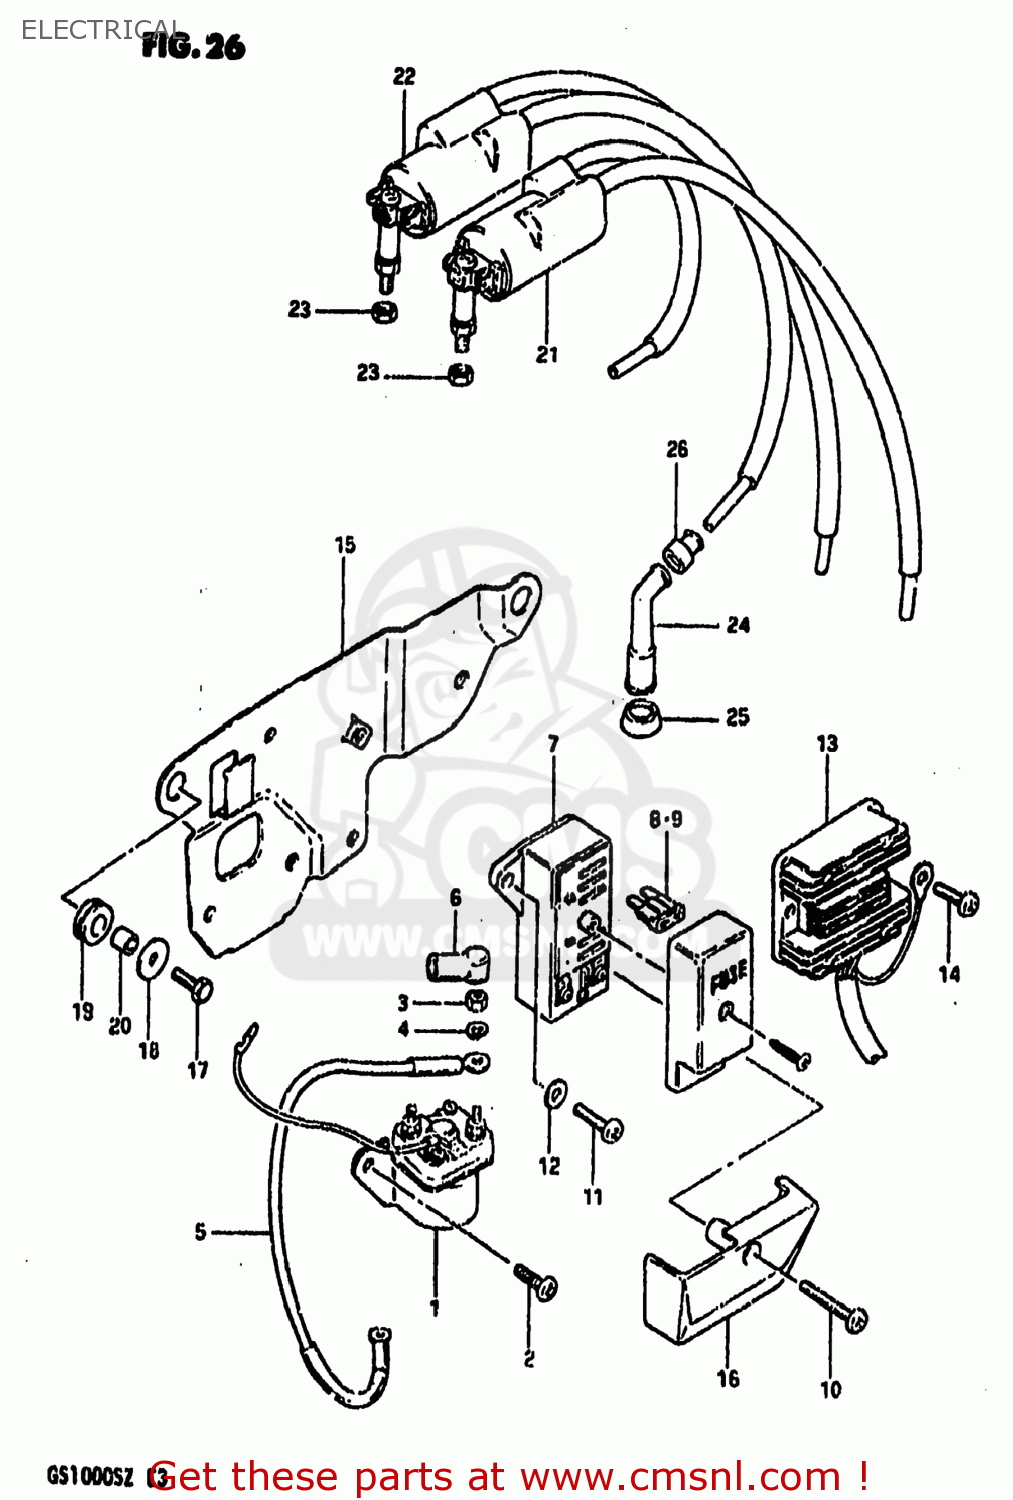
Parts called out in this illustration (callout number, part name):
1	RELAY, STARTING MOTOR
2	SCREW
3	NUT 6MM
4	LOCK WASHER
5	CORD,BATTERY MINUS
6	CAP,STARTER RELAY
7	BOX ASSEMBLY,FUSE
8	FUSE(10A)
9	FUSE(15A)
10	SCREW (6X35)
11	SCREW
12	WASHER
13	RECTIFIER, REGULATOR
14	SCREW 6X12
15	HOLDER COMP,ELECTRONIC PARTS
16	COVER,ELECTRIC PARTS HOLDER
17	BOLT, UPPER
18	WASHER (6.5X22X1.6)
19	CUSHION
20	SPACER (7X9X7)
21	COIL ASSEMBLY,IGNITION
22	COIL ASSEMBLY,IGNITION
23	NUT
24	CAP ASSY,SPARK PLUG
25	SEAL,SPARK PLUG
26	SEAL,SPARK PLU
